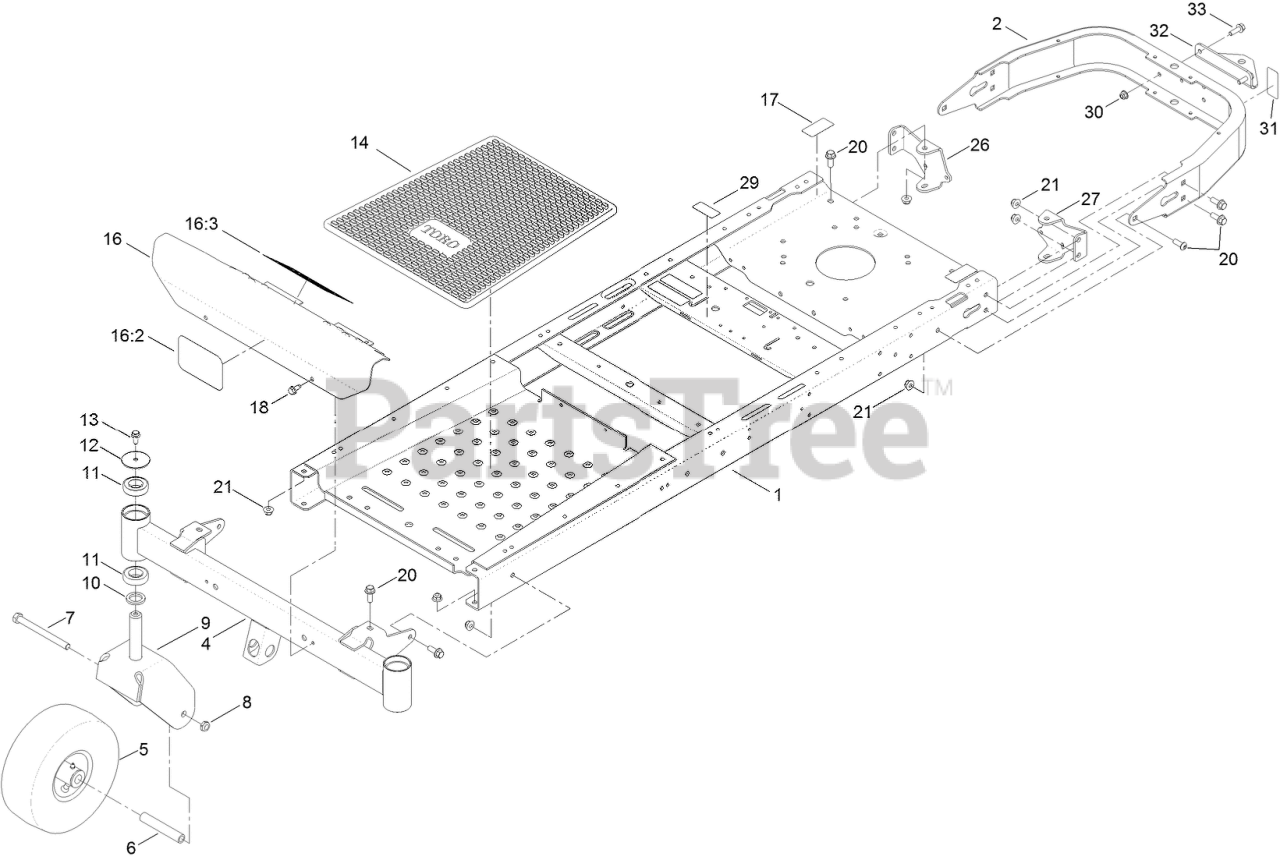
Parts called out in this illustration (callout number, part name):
2	BUMPER-REAR
4	AXLE-FRONT
5	Caster Wheel ASM
6	BUSHING-SPANNER
7	SCREW-HH
8	NUT-LOCK, NI
9	FORK-CASTER
10	WASHER-THRUST
11	BEARING-BALL
12	WASHER
13	SCREW-HHF
14	MAT-FLOOR
16	FOOTREST ASM
16:3	DECAL-DANGER
17	DECAL-BYPASS
18	SCREW-HWHTF
20	SCREW-HHF
21	NUT-HF, NI
26	MOUNT-HYDRO, REAR (RH)
27	MOUNT-HYDRO, REAR (LH)
29	DECAL-LOCATION, SERVICE DEALER
30	NUT-HF, NI
32	BRACKET-HITCH
33	SCREW-HHF
